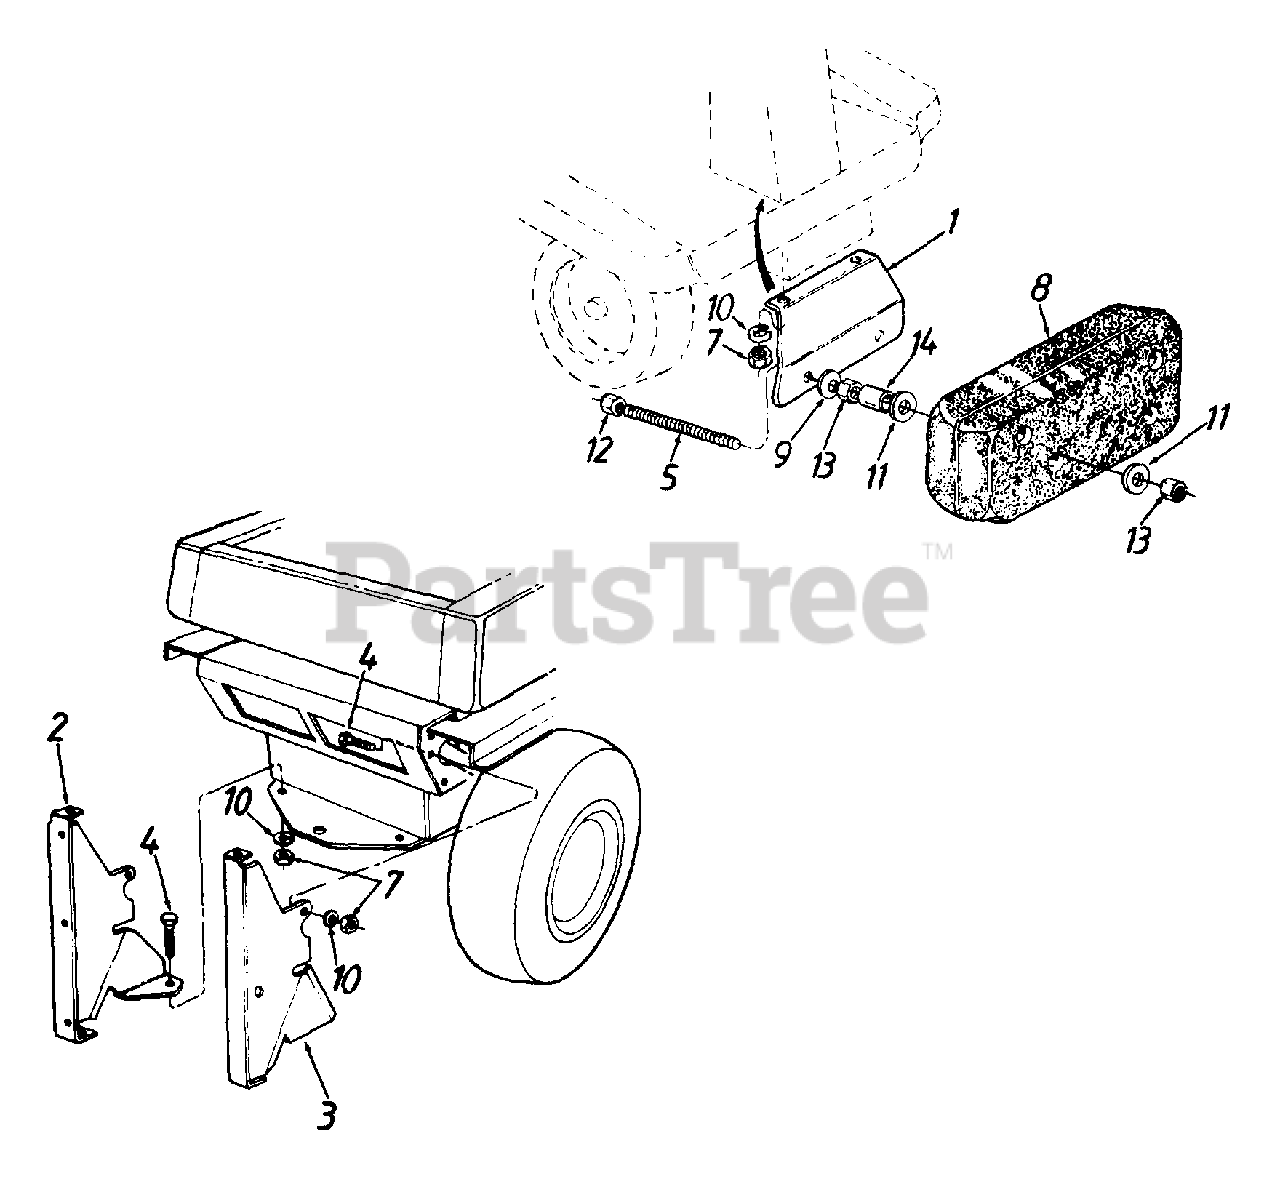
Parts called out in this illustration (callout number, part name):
3	Catcher Support Brkt. - L.H.
4	Hex Bolt 5/16-18 x 1.0" Lg.
5	Stud 7/16-14 x 5-5/8" Lg.
7	Hex Nut 5/16-18 Thd.
8	Front Counterweight
9	Bell-Wash. 7/16" I.D.
10	L-Wash. 5/16" I.D.
11	Fl-Wash. .45" I.D.
12	Hex L-Nut 7/16-14 Thd.
13	Hex Nut 7/16-14 Thd.
14	Spacer
